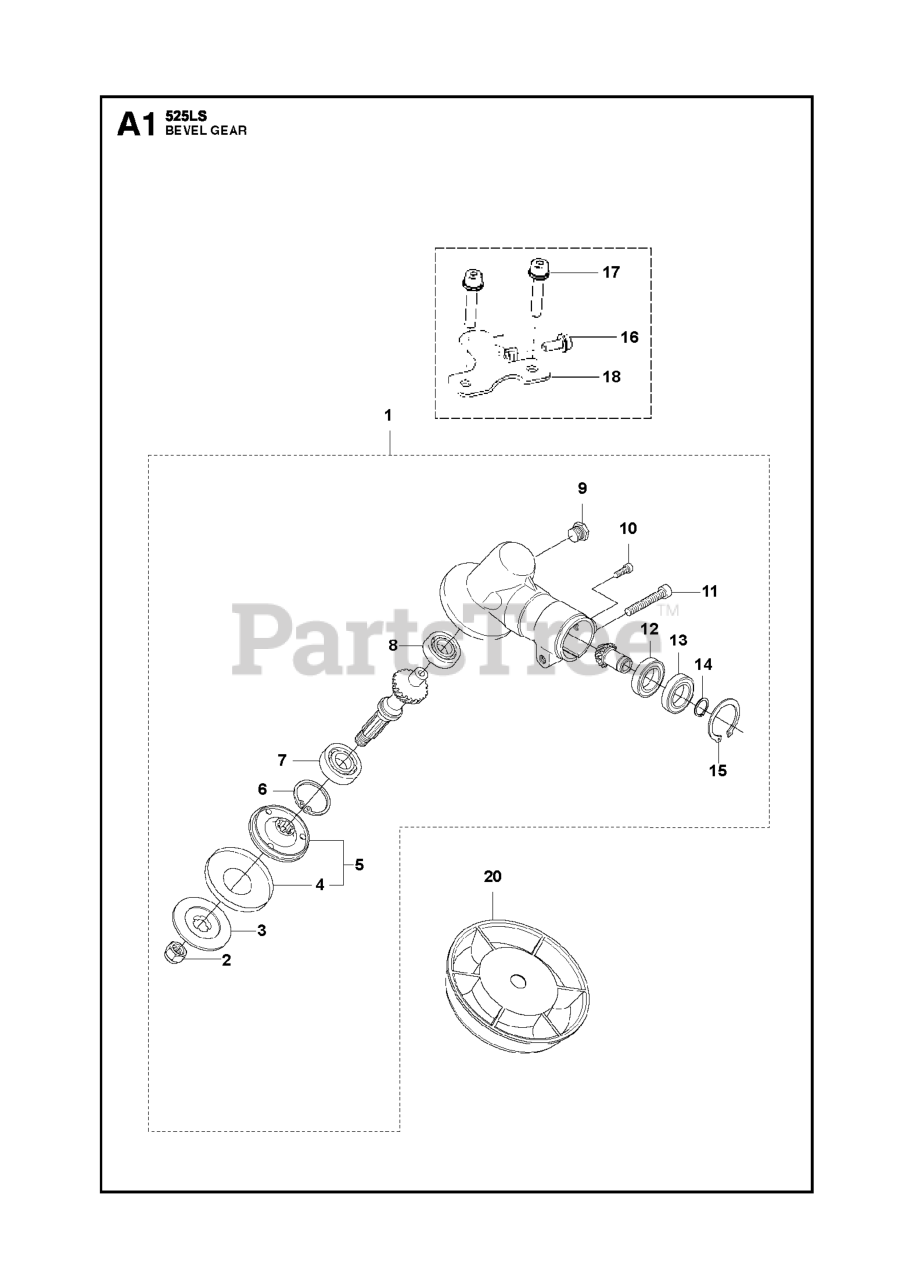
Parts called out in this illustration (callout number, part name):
1	GEAR HEAD
2	GEARHEAD NUT - BRUSHCUTTER
3	SUPPORT FLANGE
4	WASHER
5	DRIVE DISC
6	RETAINING RING SGH 28
7	BEARING
8	BALL BEARING 8X22X7/608Z
12	BALL BEARING 24X9X1/609ZR
14	RETAINING RING
15	RETAINING RING
17	BOLT, TORX
18	BRACKET SHIELD
20	SUPPORTING CUP
